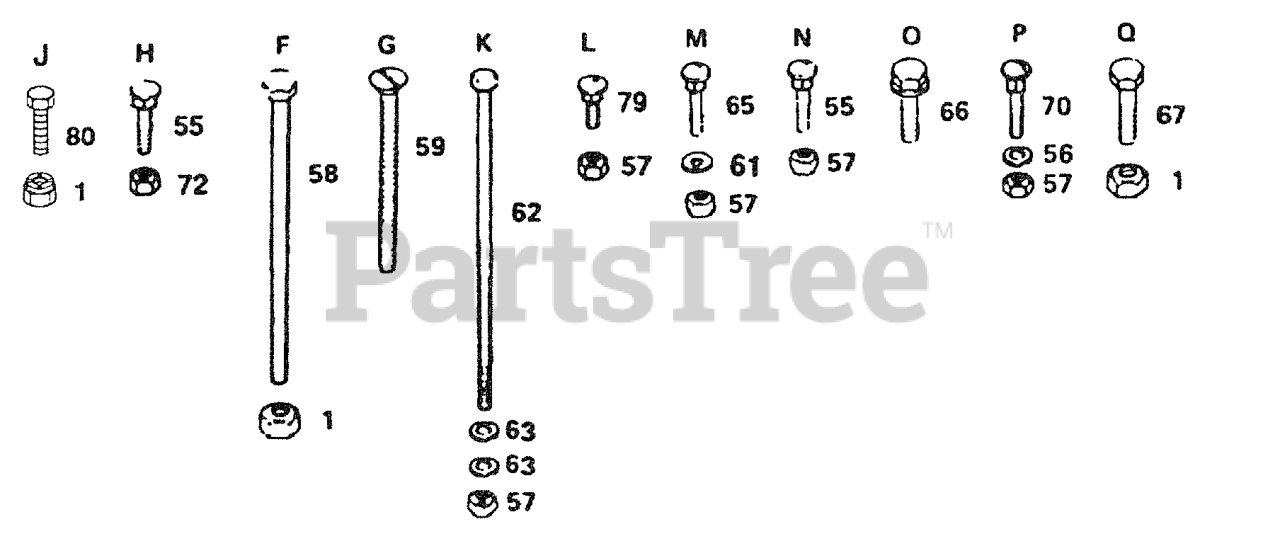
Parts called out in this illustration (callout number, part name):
55	RP BOLT 5/16-18 X3/4 ZN/YEL GR
56	WASHER
57	LOCKNUT
58	BOLT
61	WASHER M
62	Bolt-Hex 5/16-18 x 5
63	WASHER M
65	RP BOLT 5/16-18 X3/4 ZN/YEL GR
66	SCREW
67	Bolt- Carriage 3/8-16 x 3/4
70	BOLT.CARR.SQNK.5/16-18UNC.X3/4
79	BOLT.CARR.5/16-18X5/8.SHORT
80	BOLT
